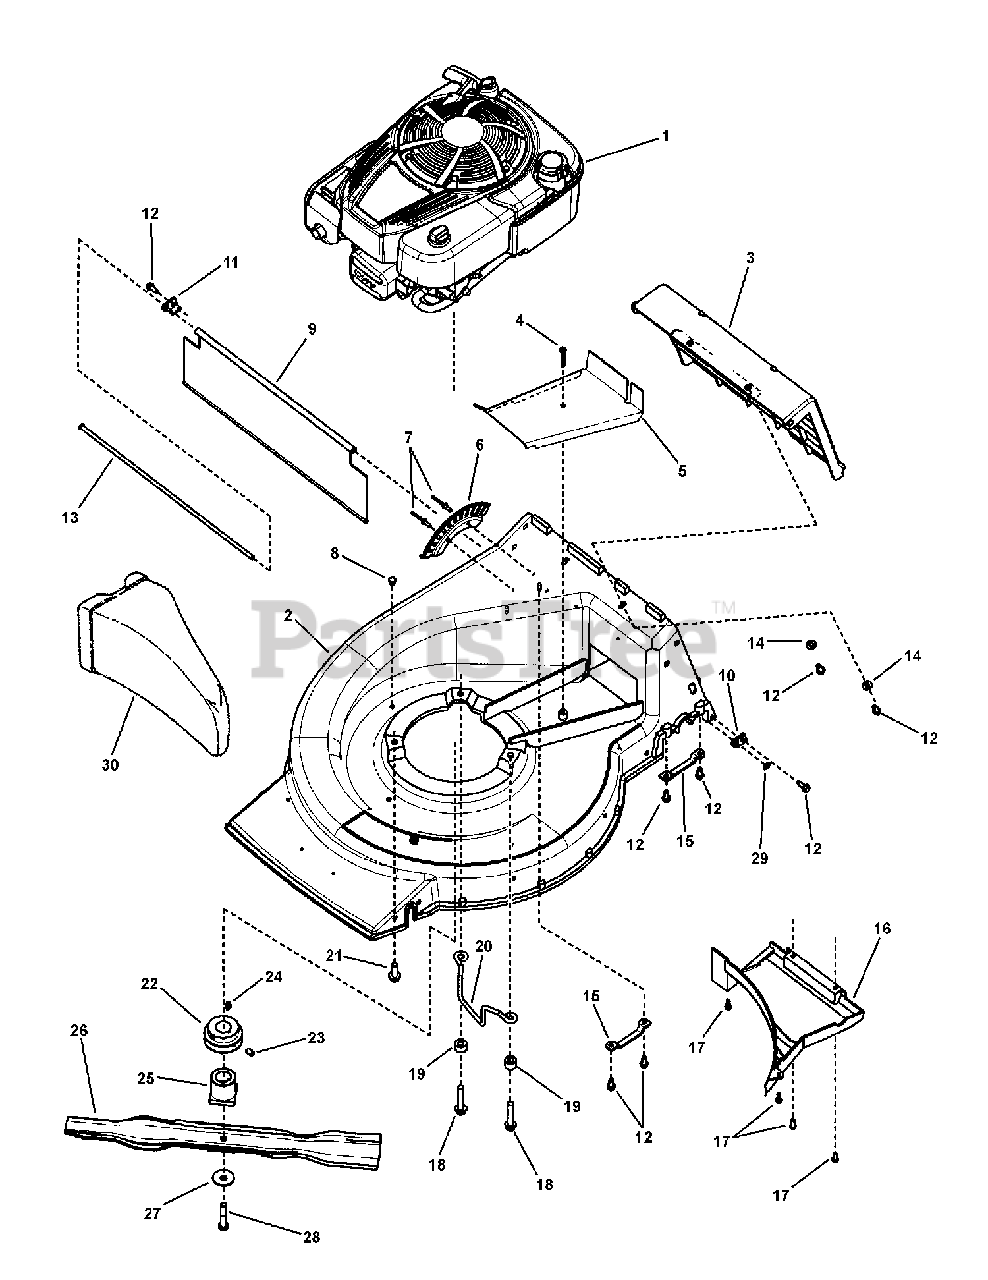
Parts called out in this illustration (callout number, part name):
1	* ENGINE, Briggs & Stratton, W14, 875 Series
2	DECK, 21" Cast Aluminum
3	ASSY, Discharge Door
4	SCREW, #10-24 x 1-1/2" Slotted Hex Washer Head Self-Tap
5	BELT COVER, Cast Deck
6	PLATE, Height Adjust
7	RIVET, 3/16" x 1/2" Steel
8	HOLE PLUG (Polyethylene)
9	SHIELD, Trailing, Commercial Cast
10	BRACKET, LH Trailing Shield Rod
11	BRACKET, RH Trailing Shield Rod
12	SCREW, 1/4-20 x 5/8" Hex Washer Face Self-Tap
13	ROD, Trailing Shield (16-1/4" long)
14	WASHER, .28 x .63 x .06 Flat
15	SUPPORT, Rear Axle
16	BAFFLE, Discharge
17	SCREW, #10-24 x 5/8" Slotted Hex Washer Head Self-Tap
18	SCREW, 3/8-16 x 2" Hex Head Self-Tap
19	IDLER SPACER
20	BELT GUIDE (Wireform)
21	SCREW, 3/8-16 x 1 Hex Washer Self-Tap
22	PULLEY, Engine
23	SET SCREW, 5/16-18 x 1/2" Hex Recess
24	KEY, Hi-Pro #HP506
25	HUB, Blade Drive 25mm I.D.
26	BLADE, Wave, 21" Steel Deck
27	WASHER, Cone
28	SCREW, 3/8-24 x 2" Hex Head Cap, GR5
29	PUSHNUT, 1/4 Black
30	PLUG, 21M Mulching
